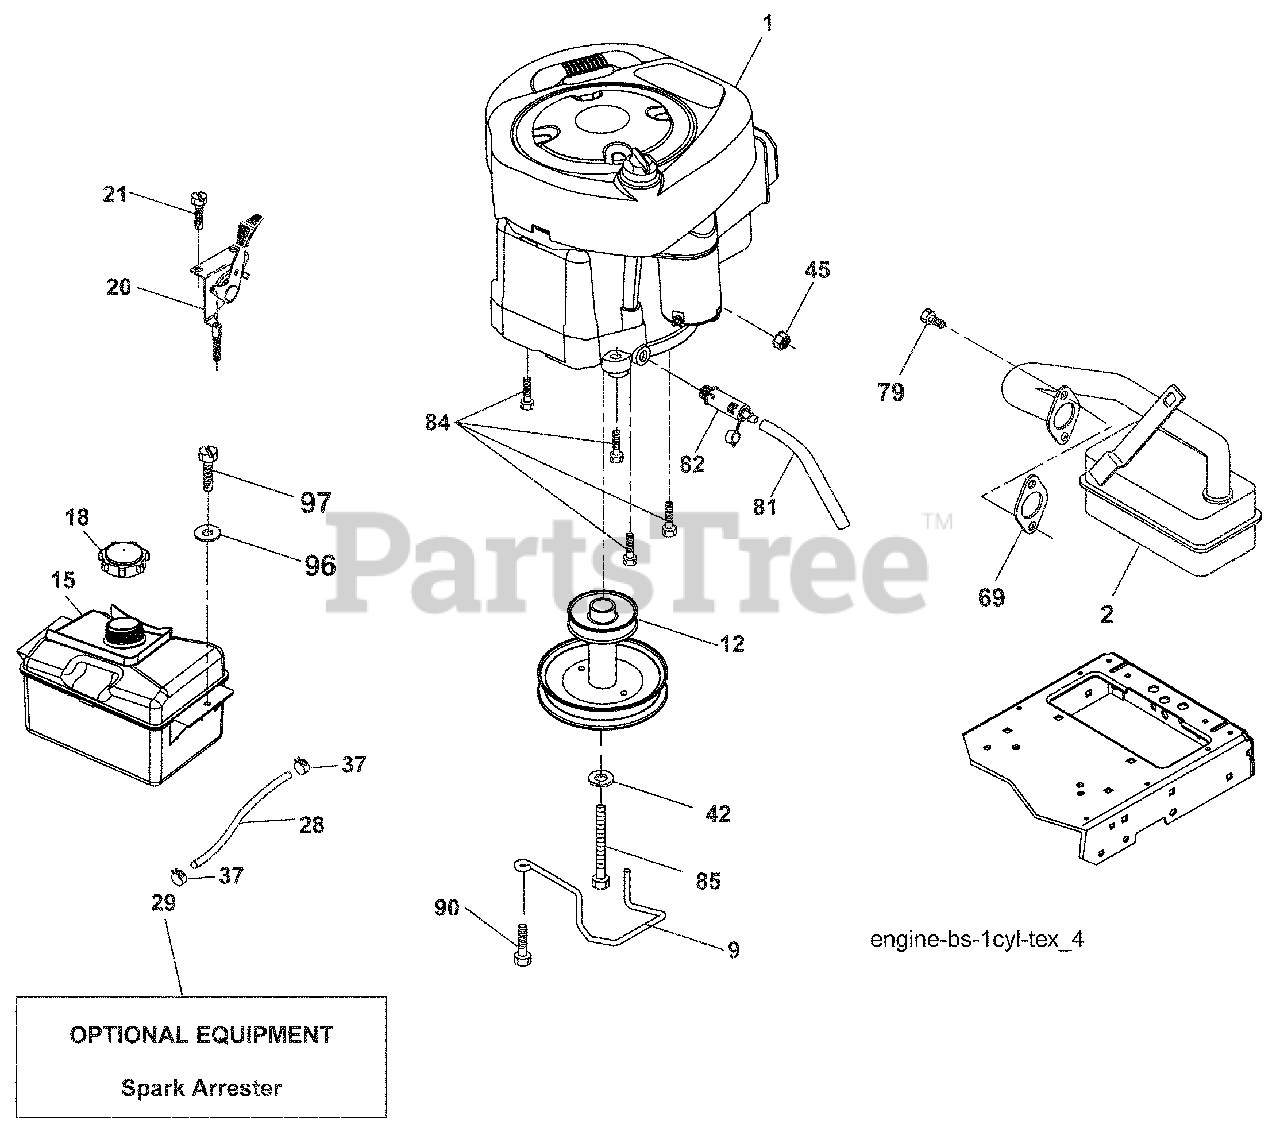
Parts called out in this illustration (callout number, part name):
1	Engine Briggs Model No. 31E677
9	Keeper Belt Engine
12	Pulley Engine
15	Tank Fuel
18	Cap Asm
20	Control Throttle
21	Screw #10 x 0.750 BOS Thread
29	Spark Arrester Kit
37	Clamp Hose
42	Washer Lock 7/16
45	Nut Keps Hex 1/4-20 unc
69	Gasket
79	Screw 5/16-18 x 3/4
81	Tube Drain Oil Easy
82	Plug Drain Oil
84	Screw 3/8-16 x 1/4
85	Bolt Hex 7/16-20 x 4 Gr. 5
90	Screw 3/8-16 x 1
96	Washer 9/32 x 7/8 x 16 Ga.
97	Screw 1/4-20 x 3/4
